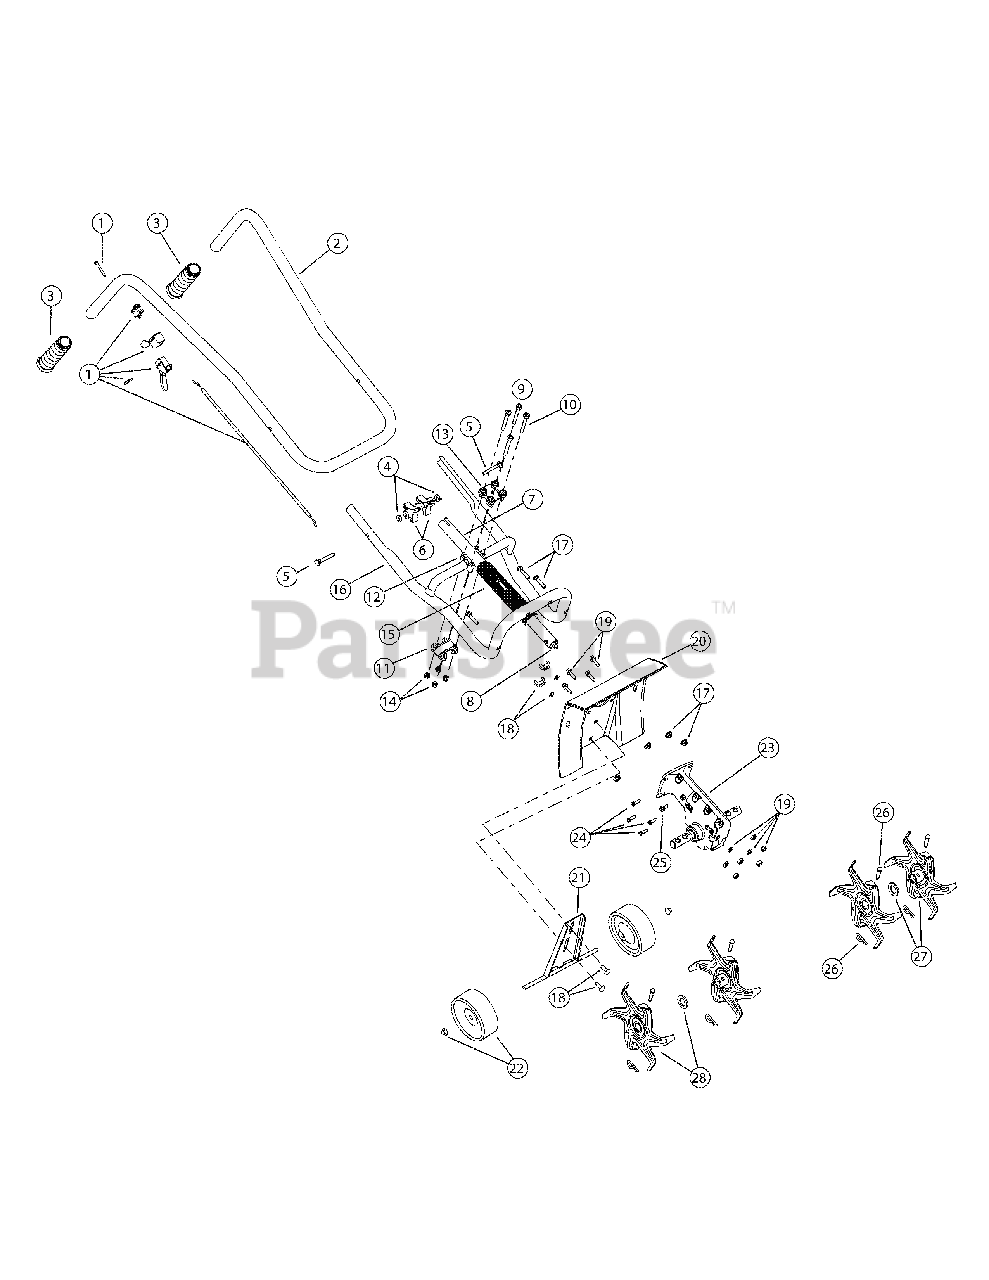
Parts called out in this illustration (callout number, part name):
1	Throttle Trigger and Cable Assembly
2	Handle Bar Assembly, Upper
4	Washer
6	Knob, 3 prong
7	Drive Shaft Housing Assembly
8	Flexible Drive Shaft
9	Handle Bracket Assembly
11	Upper Handle Clamp
12	Middle Handle Clamp
13	Lower Handle Clamp
16	Lower Handle Bar
17	Hardware, Handle Bar Mounting
18	Wheel Bracket Mounting Hardware
19	Guard Mounting Hardware
21	Wheel Bracket Assembly
22	Wheel Assembly
23	Gear Box Assembly
25	Sleeve Retainer Bolt
26	Tine Fastener Assembly
27	Tine Assembly - 2009 & After
27	Tine Assembly - 2008 & Before
28	Tine Assembly - 2009 & After
28	Tine Assembly - 2008 & Before
